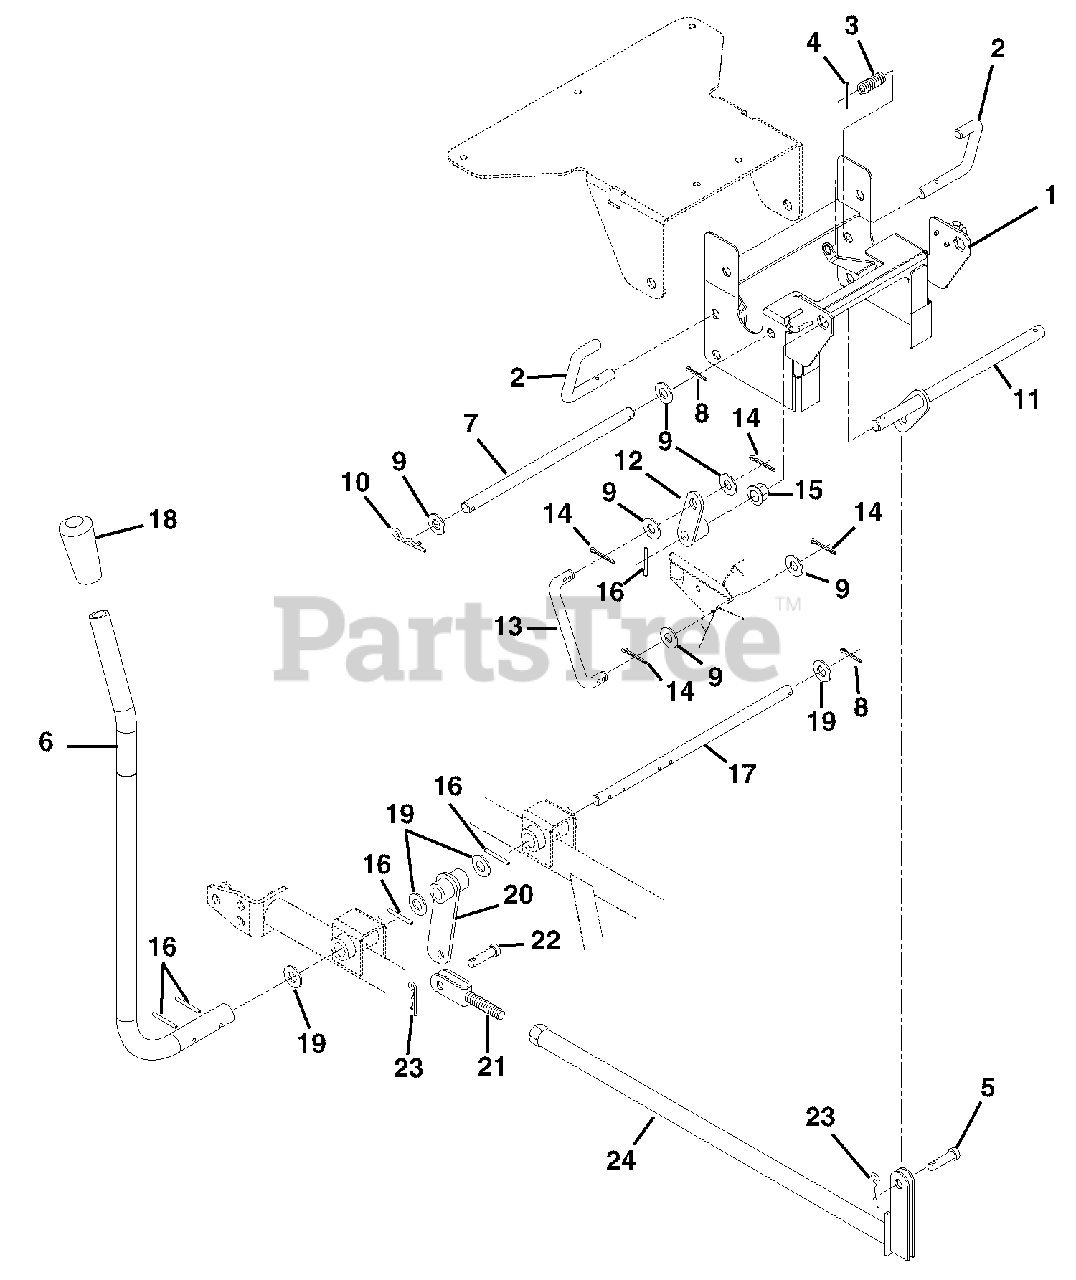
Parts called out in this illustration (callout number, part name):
1	Blade Pivot
2	Pin, Latch
3	Spring-Compression .072 x .77 x 1.75
4	Pin-Roll .188 x 1.00
5	Clevis Pin .500 Diameter x 1.00
6	Lift Lever
7	Rod, Pivot
8	Pin-Cotter .12 x 1.25
9	Washer-Flat-Steel .656 x 1.31 x .095
10	Pin-Hair-Internal .17 x .68 x 3.50
11	Pivot Rod
12	Lever-Right Hand
14	Pin-Cotter .12 x 1.0
15	Bushing-Flange .750 x .873 Hex x .53 x 1.18
16	Pin-Grove .250 x 1.50
17	Lift Shaft
18	Grip, Handlebar
19	Washer-Flat-Steel .754 x 1.125 x .062
21	Clevis, Right Hand
22	Clevis Pin .491/.496 x 1.25
23	Pin-Hair Internal .15 x 2.937
24	Lift Tube
